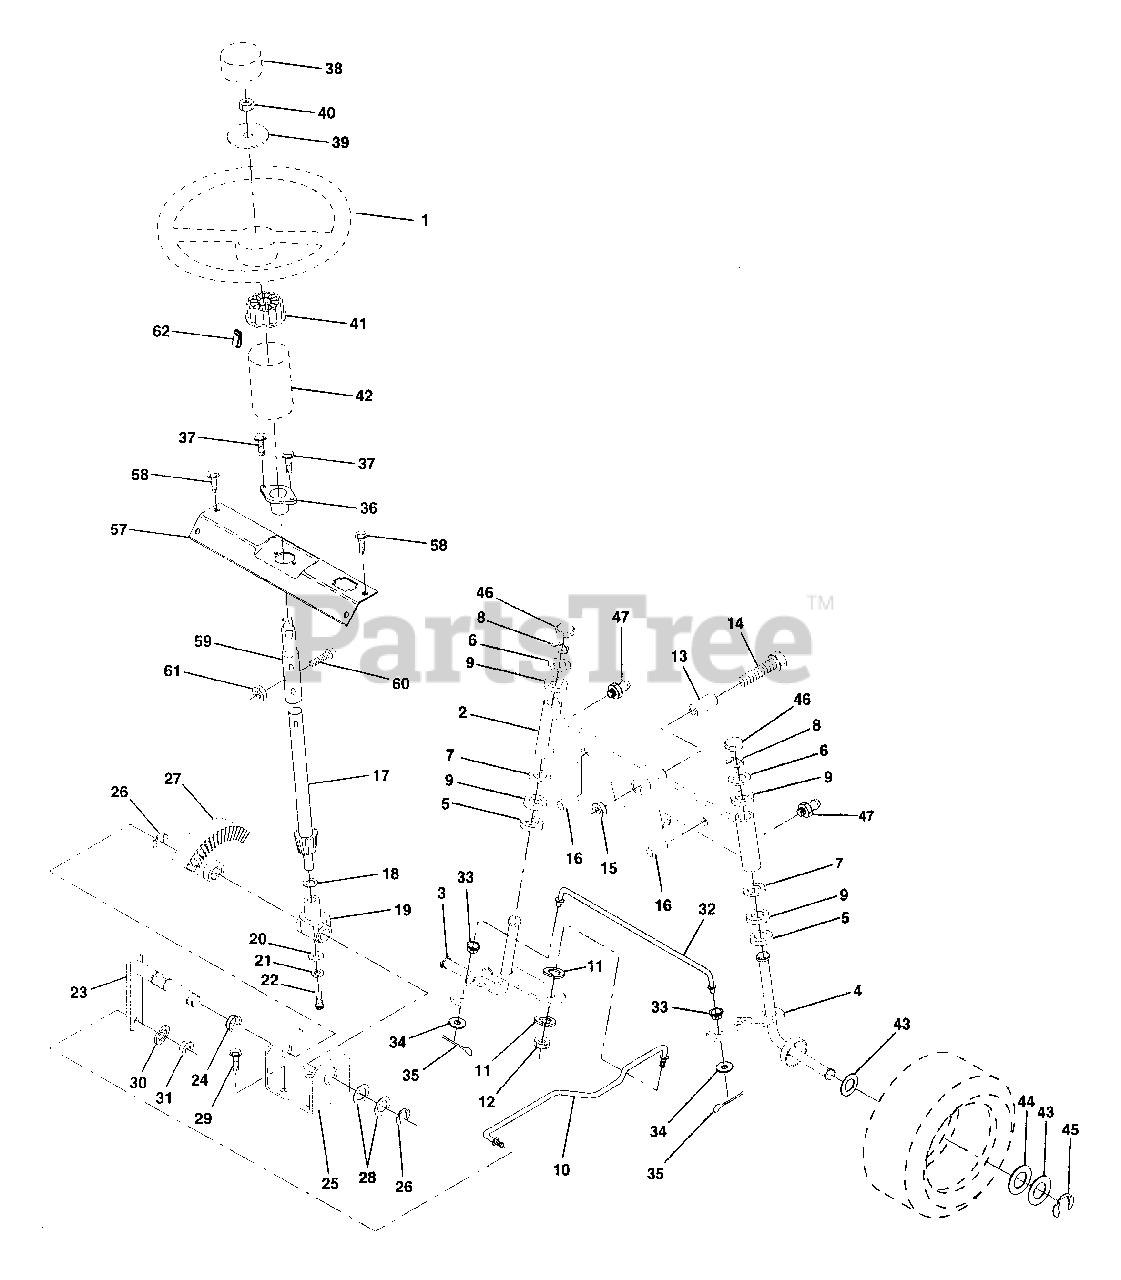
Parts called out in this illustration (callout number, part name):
1	Wheel Steering Auto Black
2	Axle Asm Fr LT W/gzks 38/42
3	Spindle Asm LH
4	Spindle Asm RH
5	Bearing Race Thrust Harden
6	Washer 25/32 X 1-5/8 X 16ga
7	Washer 27/32 X 1-1/4 X 16 Ga
8	Ring Klip #t5304-75
9	Bearing Col Strg Blk
10	Link Drag Sol Ball Jt 20 064
11	Washer Lock Hvy Hlcl Spr 3/8
12	Nut Fin Hex 3/8-24 Unf
13	Spacer Bearing Axle Front
14	Bolt Hex 5/8-11 Unc X 3-1/2
15	Nut Lock Flange 5/8-11 Unc
16	Pin Axle 5/8 X 1 55/1 54 Lg
17	Shaft Asm Strg Private Label
18	Washer Thrust 515x 750x 033
19	Support Shaft
20	Washer Shim 1/4 X 5/8 X 062
21	Washer Lock Hvy Helical 1/4
22	Screw Hex Socket 1/4-20 X 5/8
23	Shaft Asm Pittman
24	Nyliner Snap In
25	Bracket Steering
26	Ring Klip #t5304-75
27	Gear Sector 22 Teeth
28	Bearing Race Thrust Harden
29	Screw Thdrol 3/8-16x3/4 Ty-tt
30	Washer Lock Hvy Hlcl Spr 3/8
31	Nut Fin Hex 3/8-24 Unf
32	Rod Tie Wire Form 19 75 Mech
33	Bushing Link Drag Blk LR
34	Washer 13/32 X 7/8 X 16ga
35	Pin Cotter 1/8 X 3/4 Cad
36	Bushing Strg
37	Screw Slftp #10-16 X 1/2 Ty-b
38	Insert Cap Strg Wh Au Gen Blk
39	Washer 13/32 X 2-3/8 X 8 Ga
40	Nut Lock Center 3/8-24unf
41	Adaptor Wheel Strg 640/ 635id
42	Boot Shaft Steering
43	Washer 25/32 X 1 1/4 X 16 Ga
44	Washer 25/32 X 1-5/8 X 16ga
45	Ring Klip #t5304-75
46	Cap Spindle Fr Top Blk
47	Fitting Grease
57	Support Shaft Steering
58	Screw Hex Wsh Thdrol 1/4-20 x 3/4
59	Shaft Extension Steering
60	Bolt Fin Hex 5/16-18 unc x 1-1/4
61	Nut Lock Hex w/Insert 5/16-18
62	Clip Tinnerman
